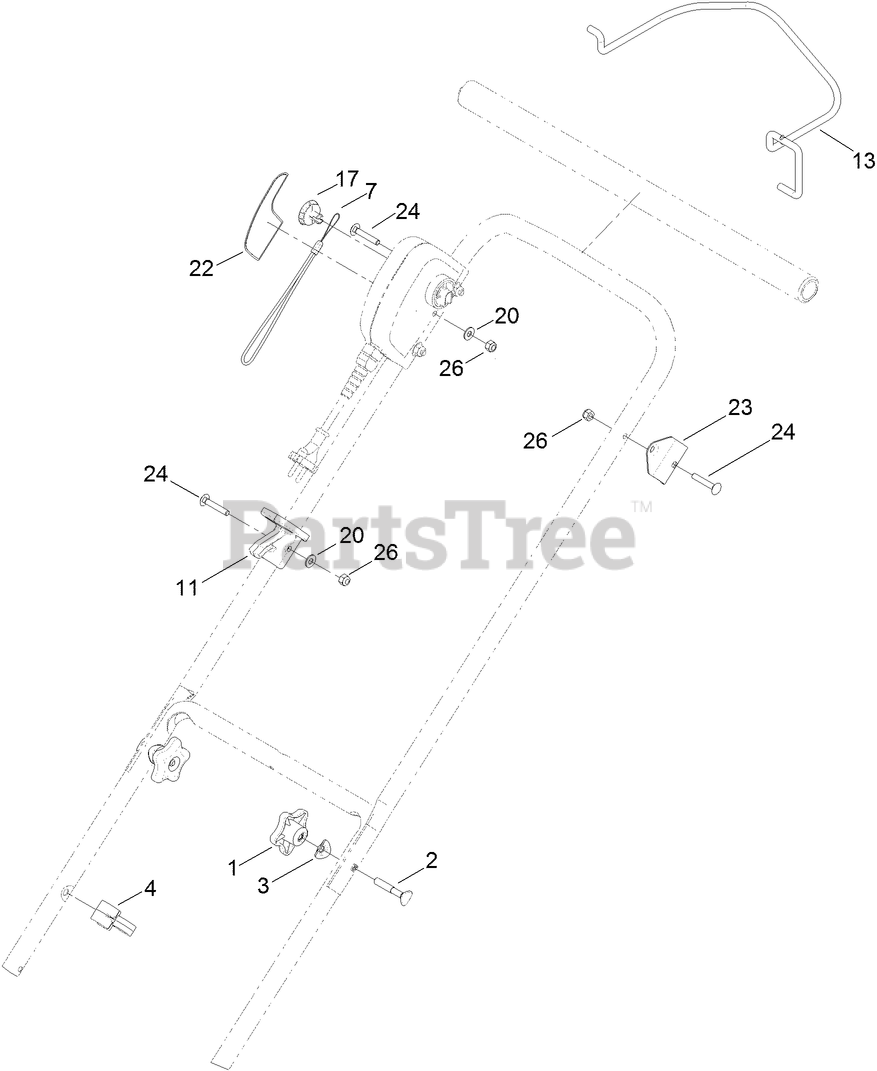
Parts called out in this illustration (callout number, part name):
1	KNOB-HANDLE
3	WASHER
4	GUIDE-CABLE
7	CORD-KEY
11	LOCK-CORD
17	KEY-BAIL
20	WASHER-FLAT
22	DECAL-OPERATION
23	BRACKET-BAIL
24	SCREW-CARR
26	NUT-LOCK, NI
